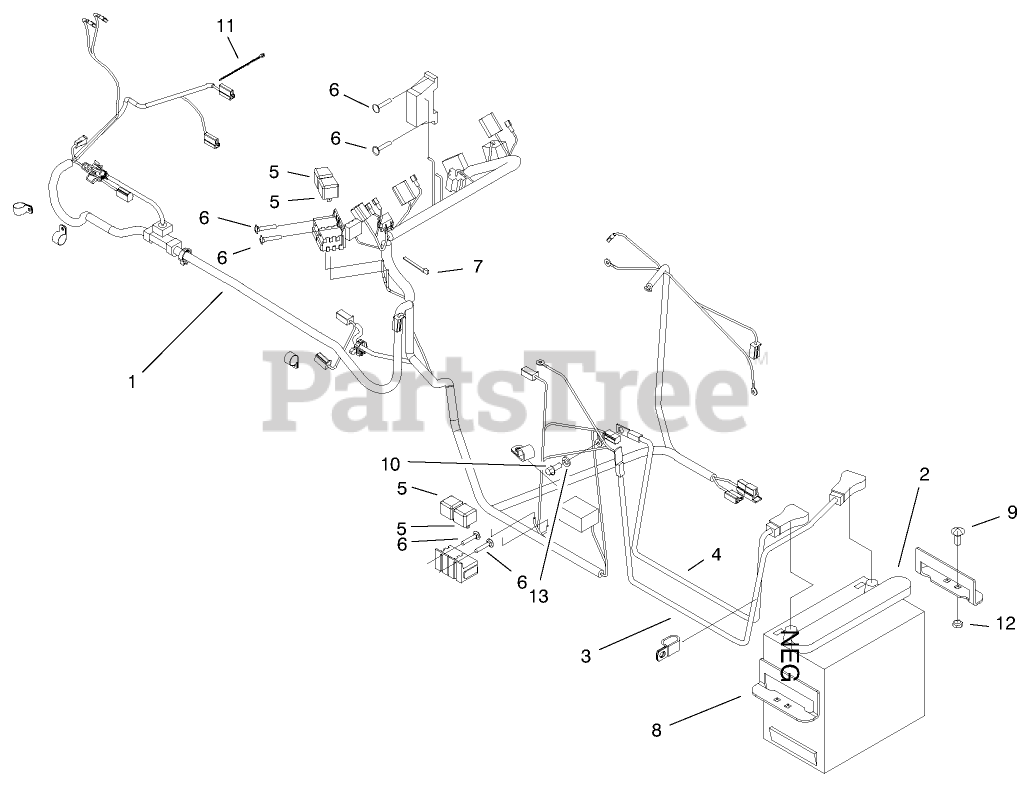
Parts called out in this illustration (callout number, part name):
1	HARNESS - MAIN
2	BATTERY, DRY - 495CCA
3	CABLE - BATTERY,RED
5	RELAY
6	SCREW
7	TIE-CABLE
8	HOLD - DOWN, BATTERY
9	SCREW-CARR
10	SCREW-HH
12	NUT-LOCK, NI
13	WASHER-LOCK
